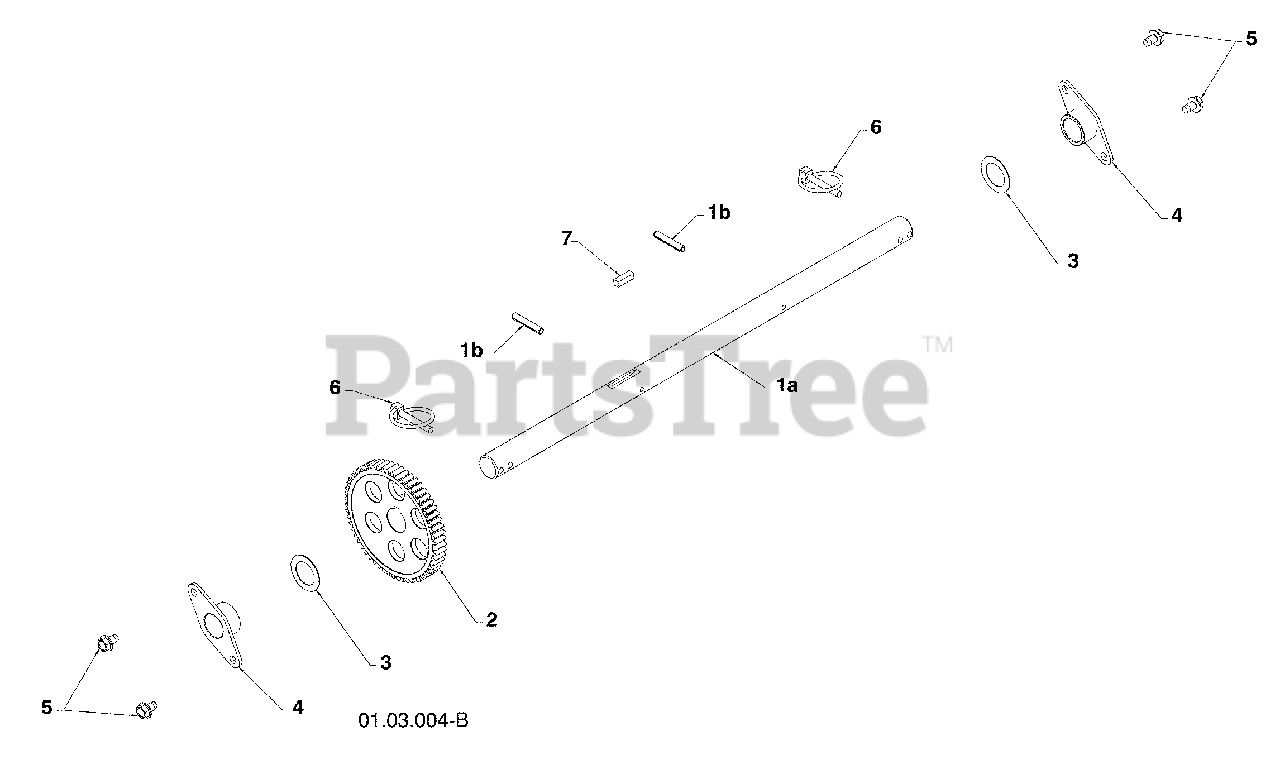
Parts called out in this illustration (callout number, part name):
1	(assy of 1a,1b) AXLE ASSEMBLY
2	GEAR
3	THRUST WASHER
5	BOLT 5/16-18 X .500
7	SQUARE KEY
